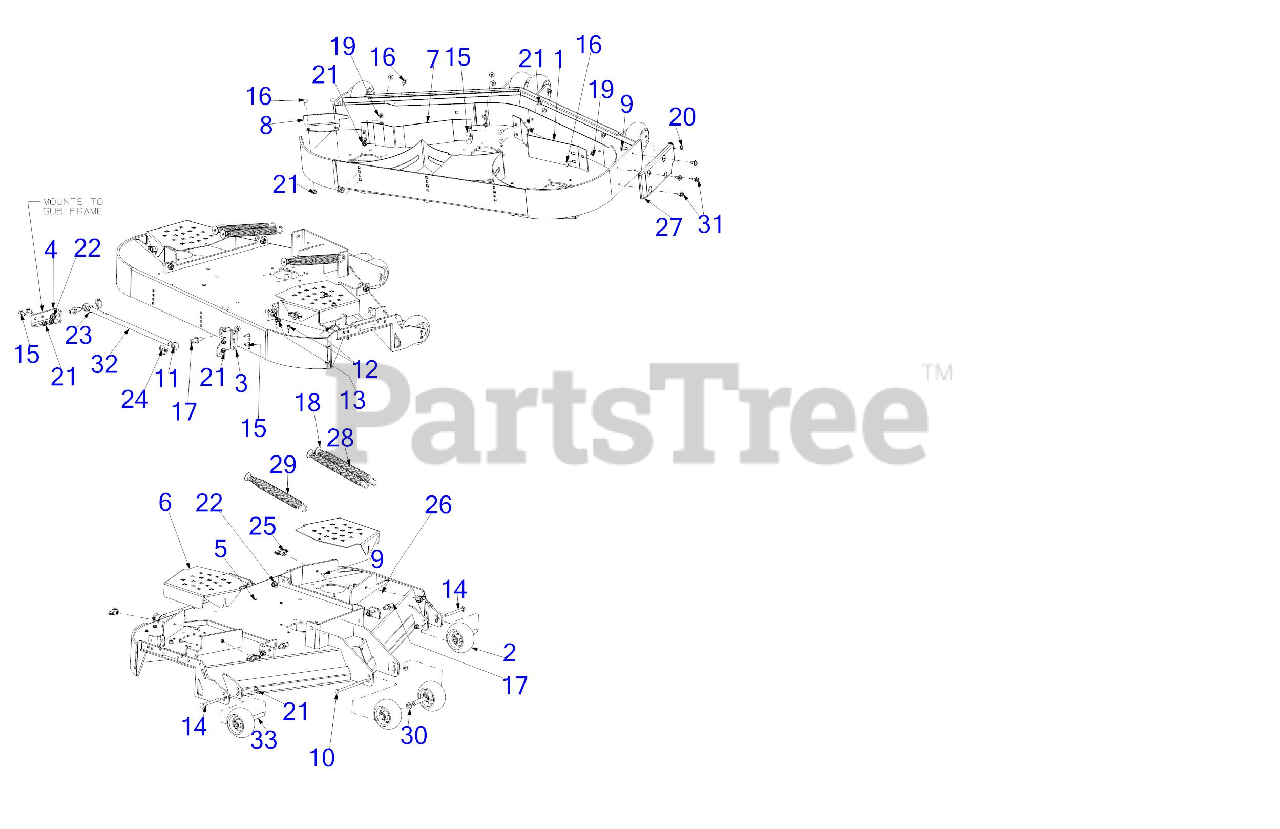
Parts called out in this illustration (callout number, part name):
1	BAFFLE - 54
2	5" DIA DECK WHEEL COMPLETE
8	DECK CHUTE BAFFLE
9	CARRIAGE BOLT 5/16-18 x 1.00
10	SCREW 3/8-16 x 7.25 GR5
11	BOLT 5/8-16 x 2.63
12	SCREW 1/4-20 X.500
13	SCREW 5/16-18 x .500
14	CARRIAGE BOLT 3/8-16 x 4.25 GR5
15	CARRIAGE BOLT 3/8-16 x 1.00 GR5
16	CARRIAGE BOLT 3/8-16 x .75
18	SPRING INSERT SCREW
20	FLANGE LOCK NUT 5/16-18
23	HEX NUT
25	WING KNOB 5/16-18
27	DECK SKID PLATE (LH)
28	EXTENTION SPRING 1.20 x 11.35
29	EXTENSION SPRING 1.44 OD X 11.36
30	FLAT WASHER .632X1.00X.16
31	SHOULDER SCREW .43X.29X5/16-18 TT
33	WHEEL SPACER .38ID x 3.04LG
